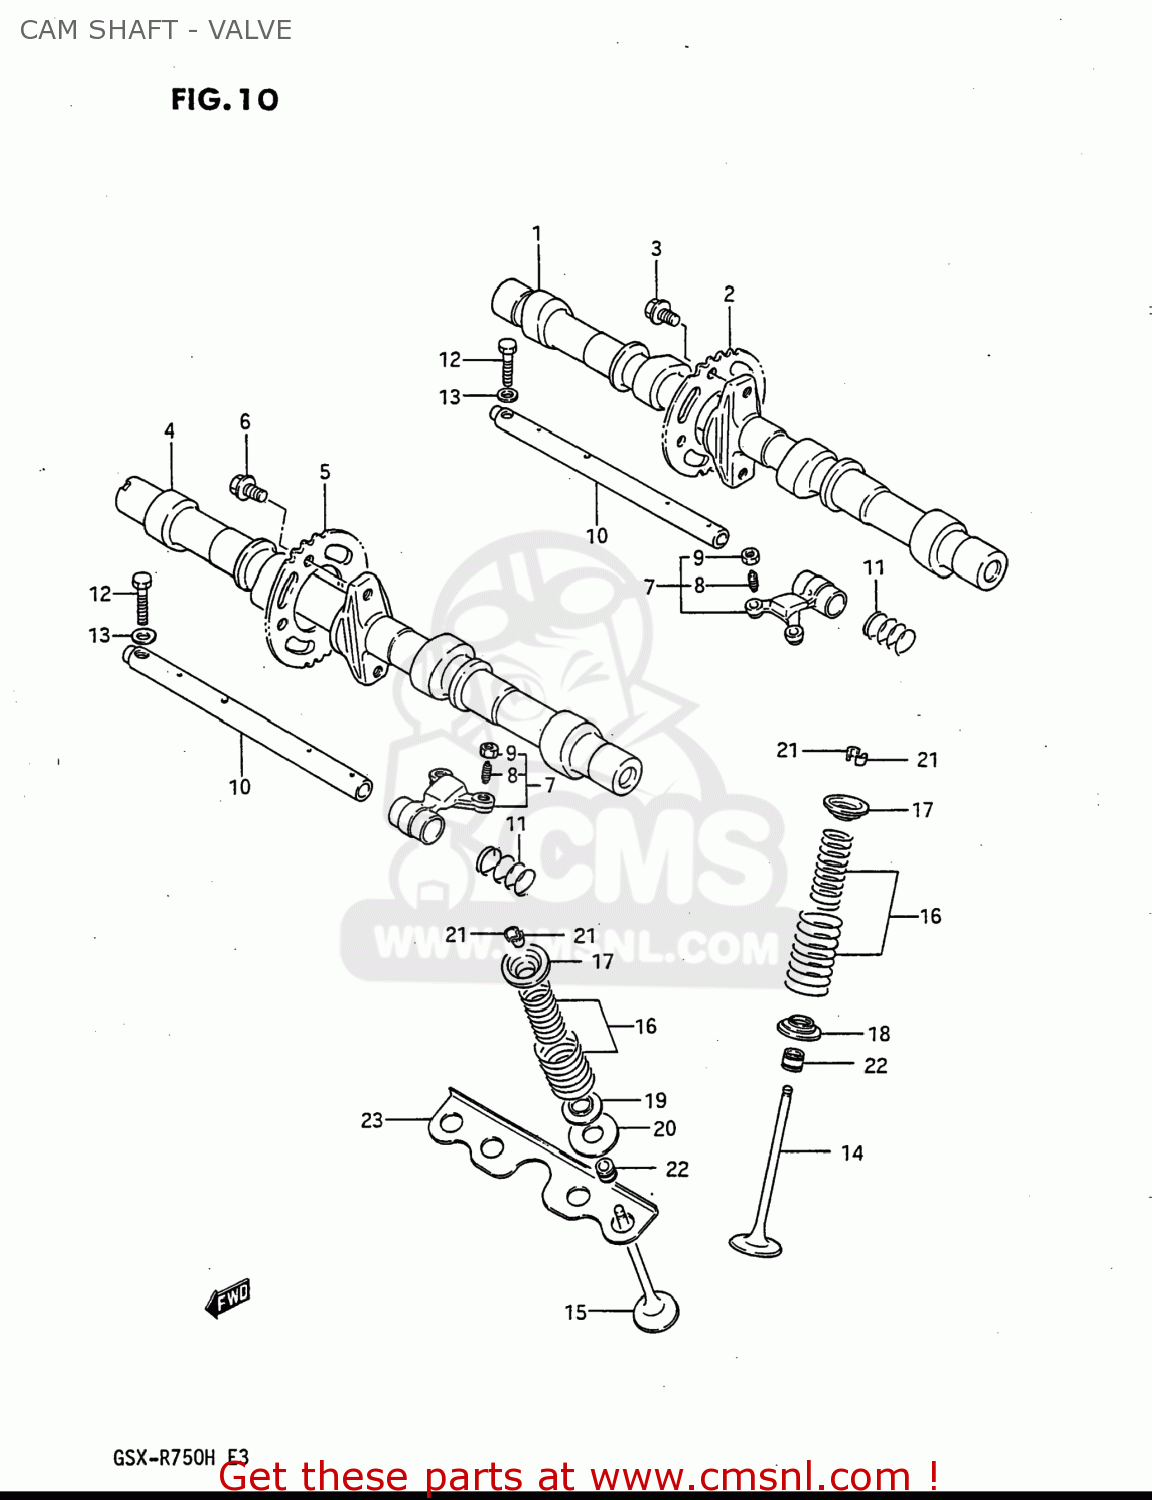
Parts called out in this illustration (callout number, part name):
1	CAMSHAFT
2	SPROCKET,CAMSHAFT
3	BOLT(7X11)
4	CAMSHAFT,EXHAUST
5	SPROCKET,CAMSHAFT
6	BOLT(7X11)
7	ARM,VALVE ROCKER
8	SCREW,TAPPET ADJUSTING
9	NUT,TAPPET ADJUSTING
10	SHAFT,VALVE ROCKER ARM
11	SPRING
12	BOLT
13	WASHER, LOWER
14	VALVE,INTAKE
15	VALVE,EXHAUST
16	SPRING SET,VALVE
17	RETAINER,VALVE SPRING
18	SEAT,VALVE SPRING
19	SEAT,VALVE SPRING
20	SEAT,VALVE SPRING EXH OUTER
21	COTTER VALVE
22	OIL SEAL
23	PLATE
